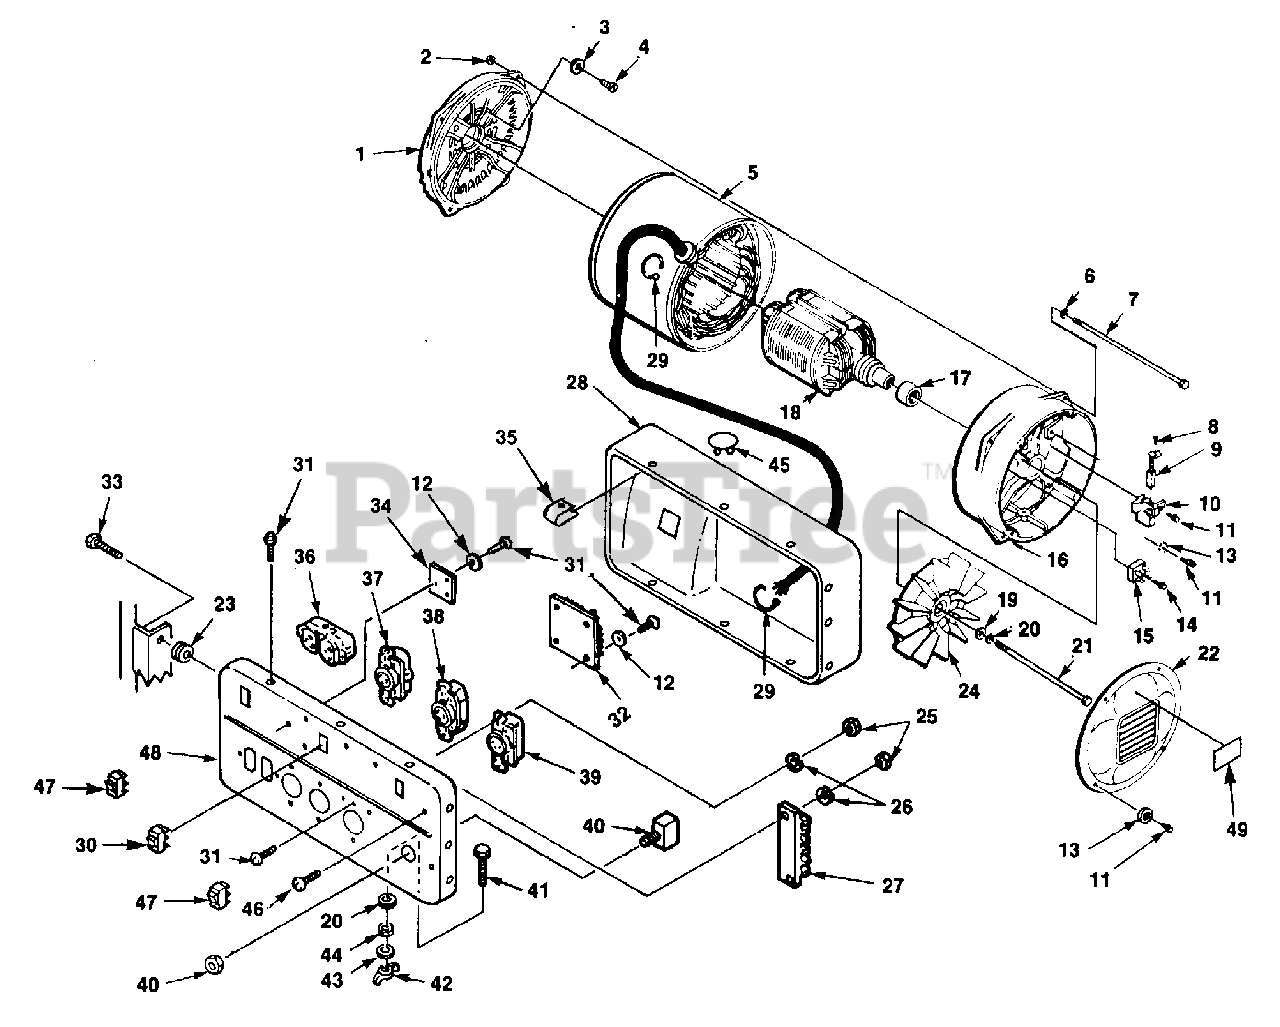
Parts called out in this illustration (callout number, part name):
1	END BELL
2	NUT-HEX 1/4-20
3	WASHER-Lock
4	SCREW-Hex-Hd 3/8-16 x 7/8
5	STATOR SHELL
6	WASHER-Lock Int. 1/4
7	BOLT- Stator
8	SCREW Mach. pan. hd. 8-32 x 3/8
10	BRUSH HOLDER
11	SCREW- Thd rolling
12	WASHER #8 flat
13	WASHER #8
14	SCREW- Hex tap. 8-32 x 3/4
15	RECTIFIER
16	BRUSH HEAD
17	BEARING
19	WASHER-Flat 5/16
20	WASHER-Lock 5/16
21	BOLT-Rotor
22	BRUSH HEAD COVER
23	GROMMET
24	FAN-Generator
25	NUT-Hex 8-32
26	WASHER-Point Set Lock #8
27	BLOCK-Terminal
28	PANEL COVER
29	CABLE-Tie
30	SWITCH (DPDT)
31	SCREW-Pan hd. #8-32 x .375
32	VOLTAGE REGULATOR
34	IDLE-Control
35	NUT-Speed
36	RECEPTACLE
37	RECEPTACLE
38	RECEPTACLE-Locking
39	RECEPTACLE-Locking
40	CIRCUIT BREAKER
41	SCREW-Hex hd. 5/16-18 x 1/8
42	WING NUT-5/16-18
43	WASHER-Lock 5/16
44	NUT-Hex 5/16-18
45	CLAMP-Cable
46	SCREW-Pan Hd 8-32 x 5/8
47	SWITCH-Rocker
48	CONTROL PANEL
49	DECAL-Warning
